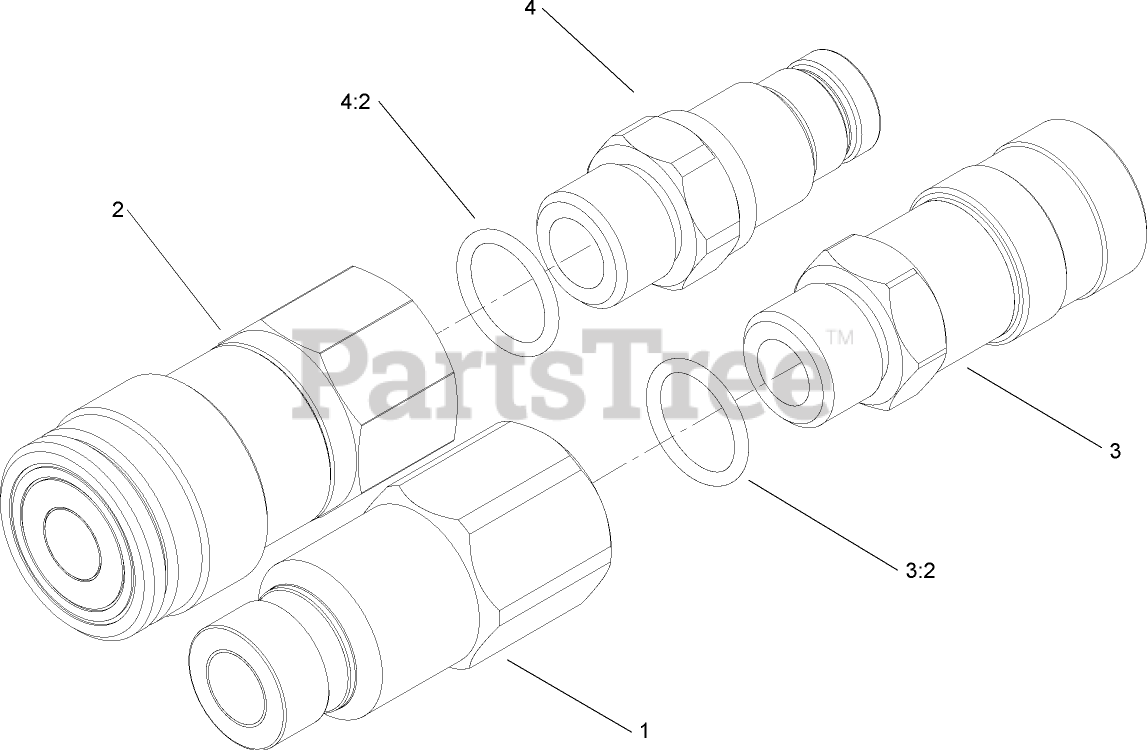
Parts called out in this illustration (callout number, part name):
1	NIPPLE-FACE, FLUSH
2	COUPLER-FACE, FLUSH
3	COUPLER-FACE, FLUSH
3:2	O-RING
4	NIPPLE-FACE, FLUSH
4:2	O-RING
